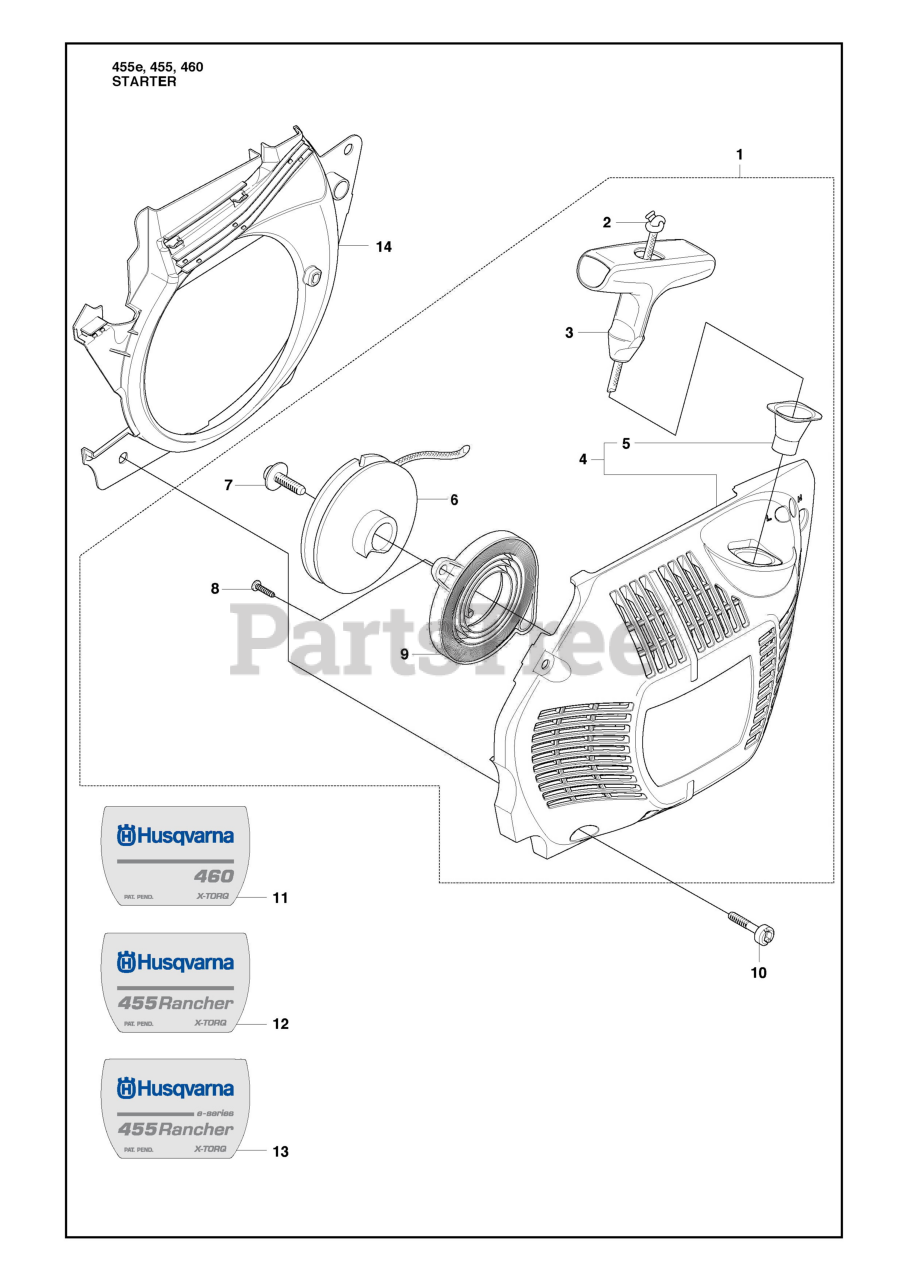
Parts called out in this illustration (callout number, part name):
1	STARTER HOUSING CPL.
2	STARTER ROPE
4	RP STARTER DEVICE
6	PULLEY
9	RETURN SPRING
10	SCREW
13	DECAL, STARTER
14	AIR CONDUCTOR
